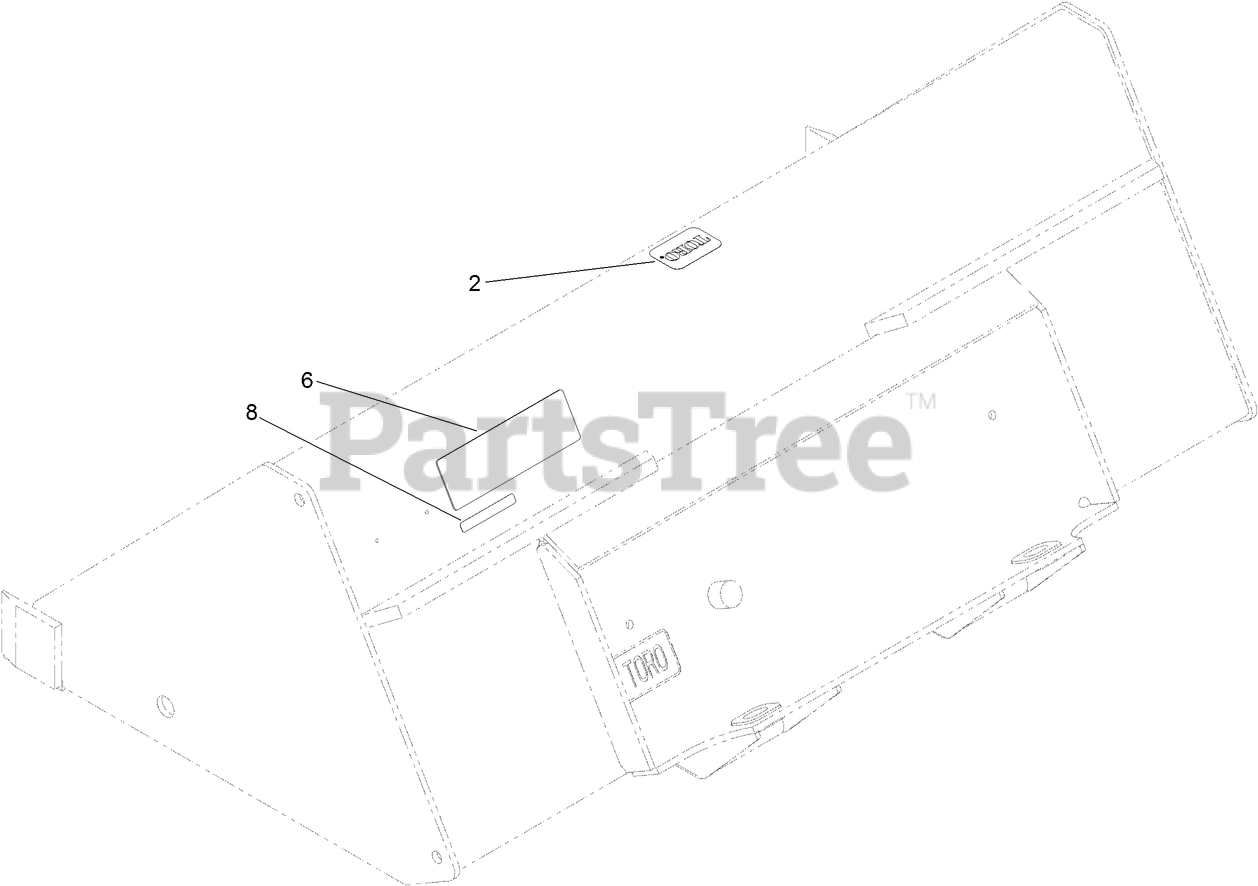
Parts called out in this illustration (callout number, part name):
2	DECAL
6	DECAL-CAPACITY
8	DECAL-WARNING
